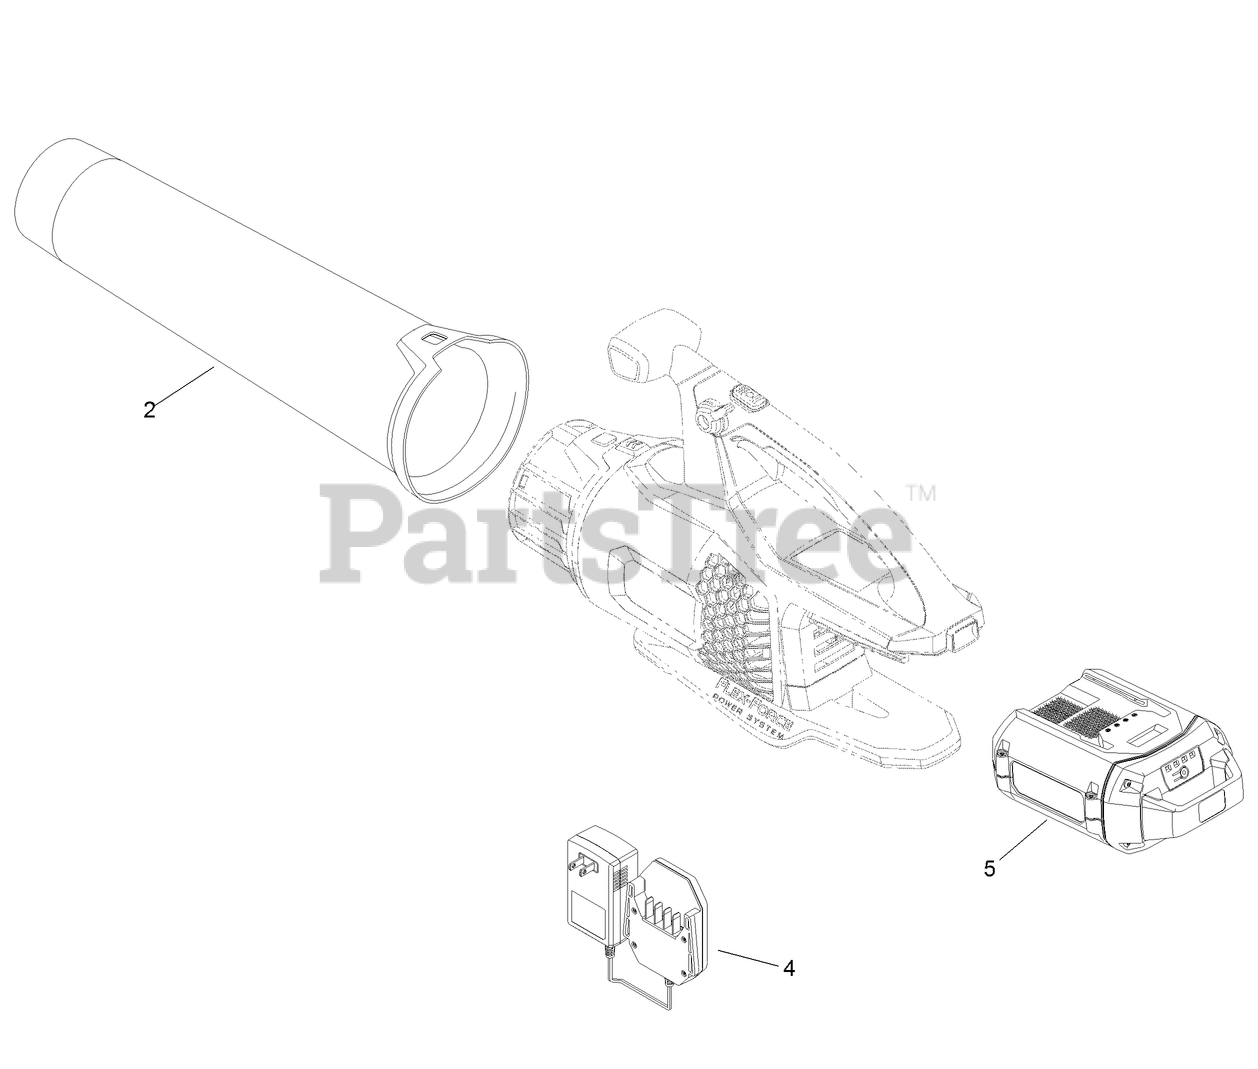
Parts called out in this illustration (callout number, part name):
2	TUBE-BLOW
4	CHARGER-BATTERY, 60V 1 AMP
5	BATTERY-60V 2.0AH
